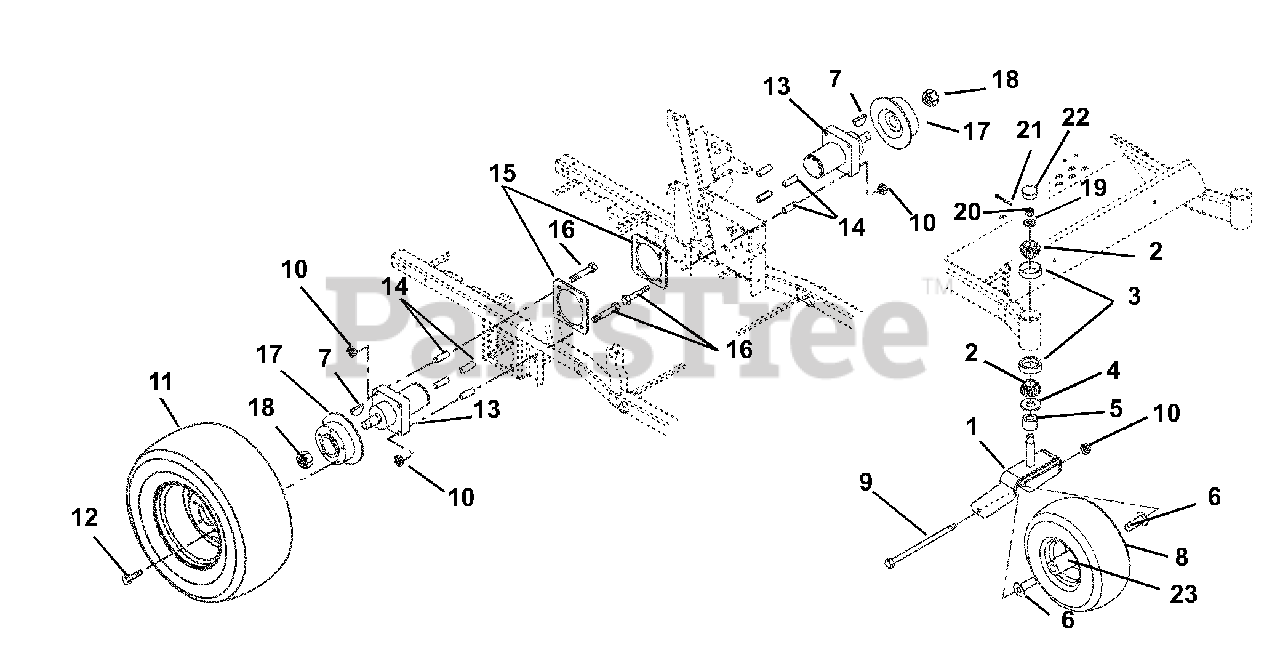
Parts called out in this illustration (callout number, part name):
1	Fork
2	Bearing, Cone with Grease
3	Bearing, Cup 1.98 x .420
4	Bearing Seal 1.5 x 2 x .18
5	Spacer, PM, 1.03 I.D. x 1.5 O.D. x .375
6	Spacer, Wheel
7	Key, Woodruff .31 x 1.00
8	Wheel/Tire Assembly
8	Tire, 15 x 6-6
9	Bolt, Hex .50-13 x 9.00 Grade 5
10	Nut, Locking Top Flange .50-13
11	Wheel, Tire Assembly 23 x 10.50-12 (080, 081, 082)
11	Tire 23 x 10.50 (078, 079, 080, 081, 082, 311)
11	Wheel, Tire 23 x 10.50 - 12 Multi-Trac (078, 079, 081, 311)
11	Wheel, Tire Assembly 23 x 9.50-12 (064, 077, 083, 310)
11	Tire, 23 x 9.50-12 Multitrac (064, 077, 083, 310)
12	Bolt, Lug Grade 8; .50-20 Unf x .75 Long 60 Degree
13	Hydraulic Wheel Motor
14	Bushing, Sleeve .513 x .748 x 2.13
15	Plate, Motor Support
16	Bolt, Hex .50-13 x 5.00 Grade 5
17	Hub and Disc
18	Nut, Lock Jam Patch
19	Washer, Flat Steel .755 x 1.375 x .062
20	Nut, Slotted .75-16
21	Pin, Cotter .16 x 1.00
22	Cap, Dust
23	Bearing, 25MM I.D. x 52MM OD x 15MM
